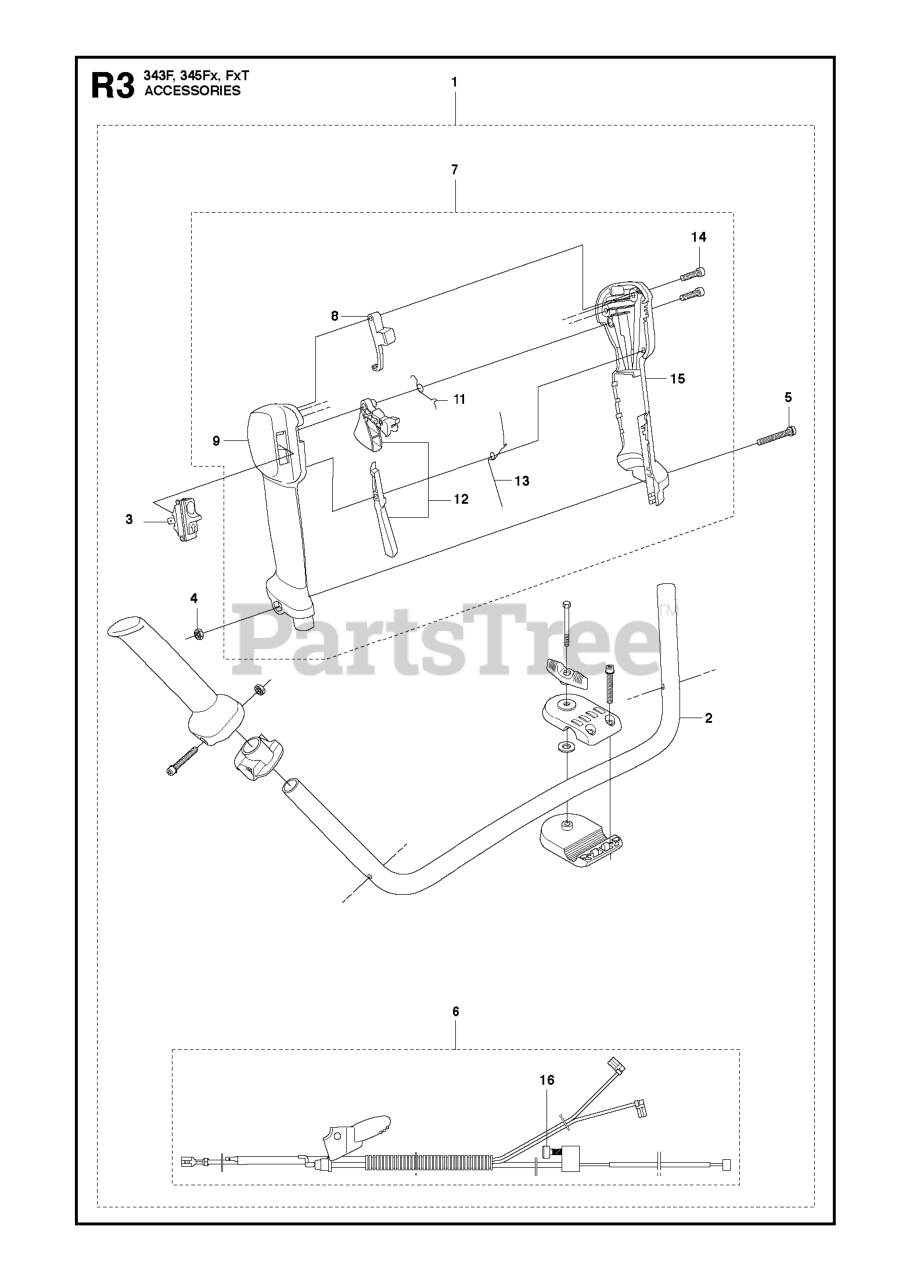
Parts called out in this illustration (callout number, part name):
2	HANDLE
3	STOP BUTTON
5	SCREW
6	WIRING ASSY
7	THROTTLE HANDLE ASSY
8	LOCKOUT STARTER THROTTLE
9	HANDLE HALF LEFT
12	THROTTLE CONTROL
15	HANDLE HALF RIGHT
16	SCREW
